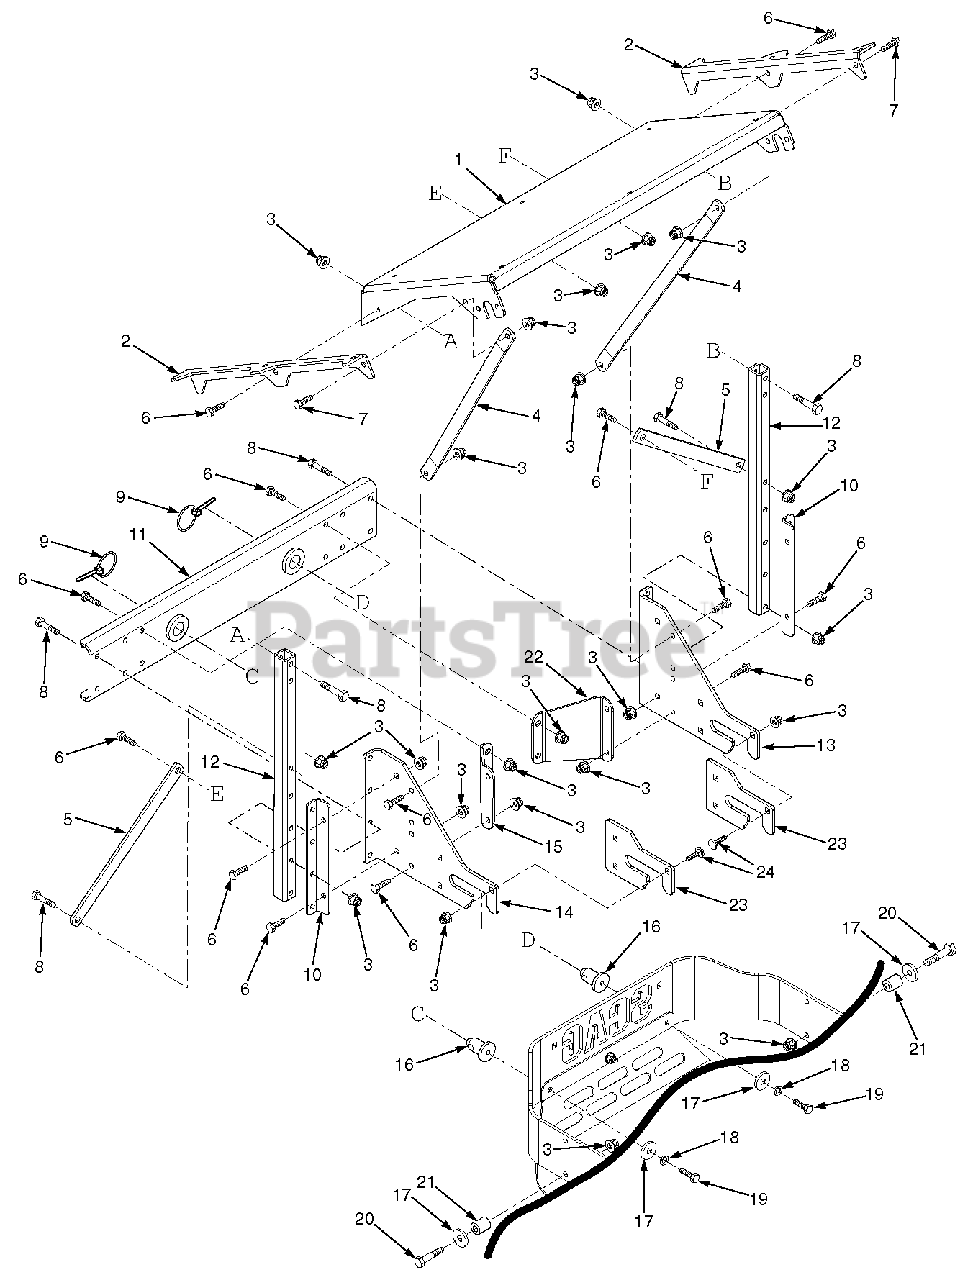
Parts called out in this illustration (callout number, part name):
1	Support Frame, Hopper
2	Bracket, Hopper Support
3	Nut, Elastic Flange 3/8-16
4	Brace, Stiffener
5	Brace, Engine Mount
6	Bolt, Hex Head 3/8-16 x 1"
7	Bolt, Hex Head 3/8-16 x 1-1/4"
8	Bolt, Hex Head 3/8-16 x 2-1/4"
9	Quick Pin
10	Mounting Bracket, Tube
11	Mounting Bracket Weldment
12	Tube, Upright
13	Mounting Bracket, GC R.H.
14	Mounting Bracket, GC L.H.
15	Angle Bracket, GC
16	Pin, GC Locator
17	Flatwasher, 3/8-.406 x 1.50 x 7 Ga.
18	Lockwasher, 3/8"
19	Bolt, Hex Head 3/8-16 x 1-1/4"
20	Bolt, Hex Head 3/8-16 x 2-1/4"
21	Spacer
22	Angle Bracket, GC
23	Wear Plate, GC
24	Bolt, Carriage 3/8-16 x 1-1/4"
